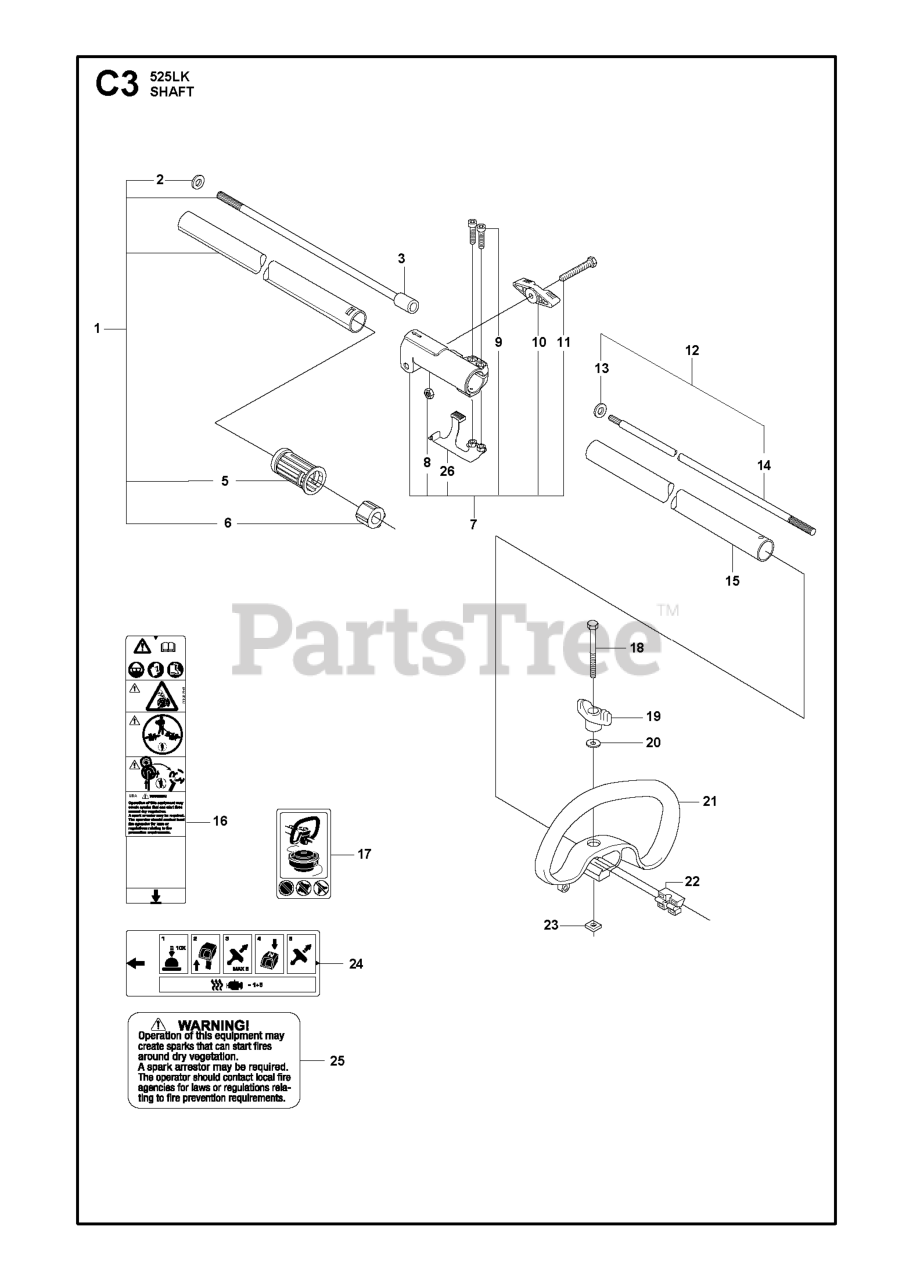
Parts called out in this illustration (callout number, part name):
1	TUBE COMP LOWER 525LDX
3	SHAFT LOWER
5	PLUG
7	CLAMPING SLEEVE ASSY
10	KNOB CLAMPING SLEEVE
11	SCREW
12	DRIVE SHAFT COMPL
14	DRIVE SHAFT
15	TUBE COMP UPPER 525LDX
16	LABEL WARNING TRIMMERS AND BRU
17	DECAL WARNING "NO BLADES"
18	BOLT
18	SCREW M6X50
19	KNOB
20	WASHER
22	SPACER PLASTIC
24	DECAL START REMINDER 523/525
25	DECAL SPARK ARRESTOR WARNING
26	LOCKING PLATE ASSY CLAMPING SL
